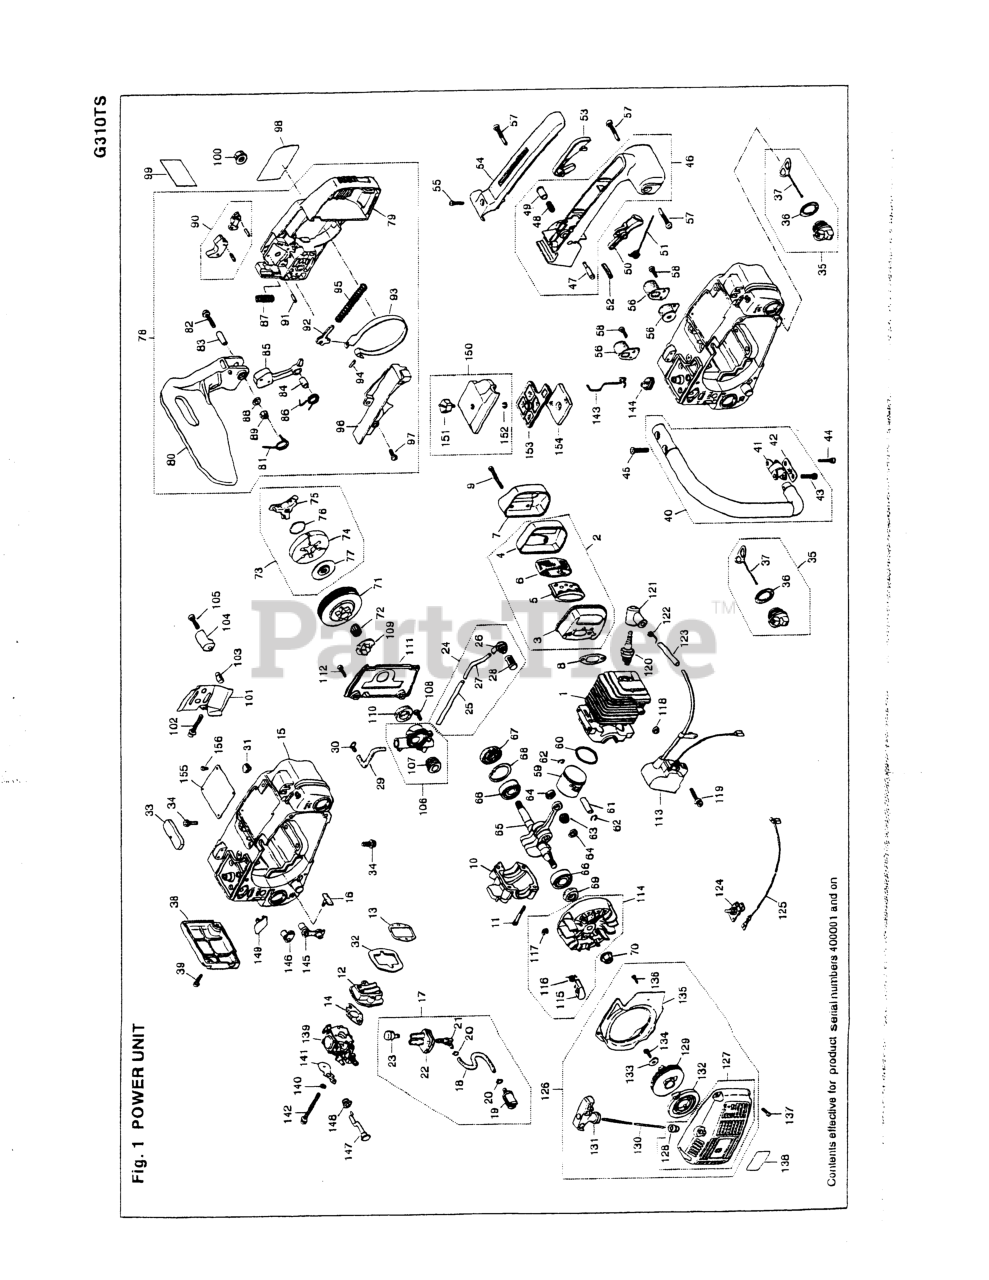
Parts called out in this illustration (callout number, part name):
1	CYLINDER
2	MUFFLER ASS
4	COVER
5	BAFFLE
6	ARRESTER
8	GASKET
10	CRANKCASE
11	BOLT, M5 X 30
12	VALVE ASSEMBLY
13	GASKET (USE -22211)
14	GASKET, CARB (USE -14121)
15	CASE (RPLS 2870-31103)
17	PIPE COMP (USE -31202)
18	PIPE (USE -85411)
19	5500-85400 (RRLS. 1750-85300)
20	CLIP (REPLACES 2841-31280)
22	GROMMET
23	BREATHER ASSY (RPLS 2630-31270
24	PIPE ASSEMBLY
25	PIPE (USE -85411)
26	GROMMET (RPLS -31320)
29	PIPE (USE -85411)
30	PIN
31	VALVE A
32	SEAL
34	SCREW
36	GASKET
37	STOPPER (RPLS 3317-57240)
38	COVER (RPLS -31912)
39	SCREW
40	HANDLE, FRONT (RPLS -32102)
41	JOINT (RPLS -32120)
42	STOPPER (RPLS -32150)
46	HANDLE, REAR (RPLS -33101)
47	STOPPER
49	KNOB
50	LEVER, THROTTLE (RPLS -33310)
51	SPRING
53	ARM (USE -33352)
55	SCREW
56	JOINT (RPLS -33510)
58	SCREW (REPLACES 50030272)
59	PISTON
60	RING
61	PIN, PISTON
62	RING, SNAP
63	BEARING
64	WASHER (RPLS 3310-41341)
65	CRANKSHAFT
67	SEAL, OIL
68	RING, SNAP, M32 x 1.2
69	SEAL, OIL (RPLS 1100-21210)
71	DRUM (RPLS 2631-51111)
72	BEARING
76	SPRING
77	BOSS (A)
78	BRAKE ASSY (RPLS -54003)
79	COVER (USE -53115)
82	SCREW
84	SPACER (RPLS -54210)
88	WASHER, M5 X .8
89	NUT (B)
90	LEVER, BRAKE COMPLETE
92	ARM, SLIDE
93	BAND
94	PIN
95	SPRING, BRAKE (RPLS. 50030121)
97	SCREW (REPLACES 50030272)
98	LABEL (RPLS-53120)
100	NUT
103	NUT
104	CATCHER, CHAIN (RPLS. -53411)
107	GEAR
109	PLATE
110	SEAL
111	COVER, PUMP (RPLS -55311)
112	SCREW
114	ROTOR (RPLS -71200)
115	PAWL (RPLS -71220)
116	SPRING (RPLS -71230)
117	RING, SNAP, M4
119	BOLT
122	SPRING
124	SWITCH A
126	STARTER ASSEMBLY
128	GUIDE (RPLS -75120)
129	REEL (RPLS -75211 & -75210)
131	KNOB (RPLS -75420)
132	HOLDER COMPLETE
136	SCREW (REPLACES 50030272)
137	SCREW
139	CARBURETOR (USE 2875-81001)
144	GROMMET
145	GROMMET A
147	ROD (RPLS -82310)
148	GROMMET
149	CAP
152	RING, SNAP, M4
155	LABEL (RPLS -31410)
